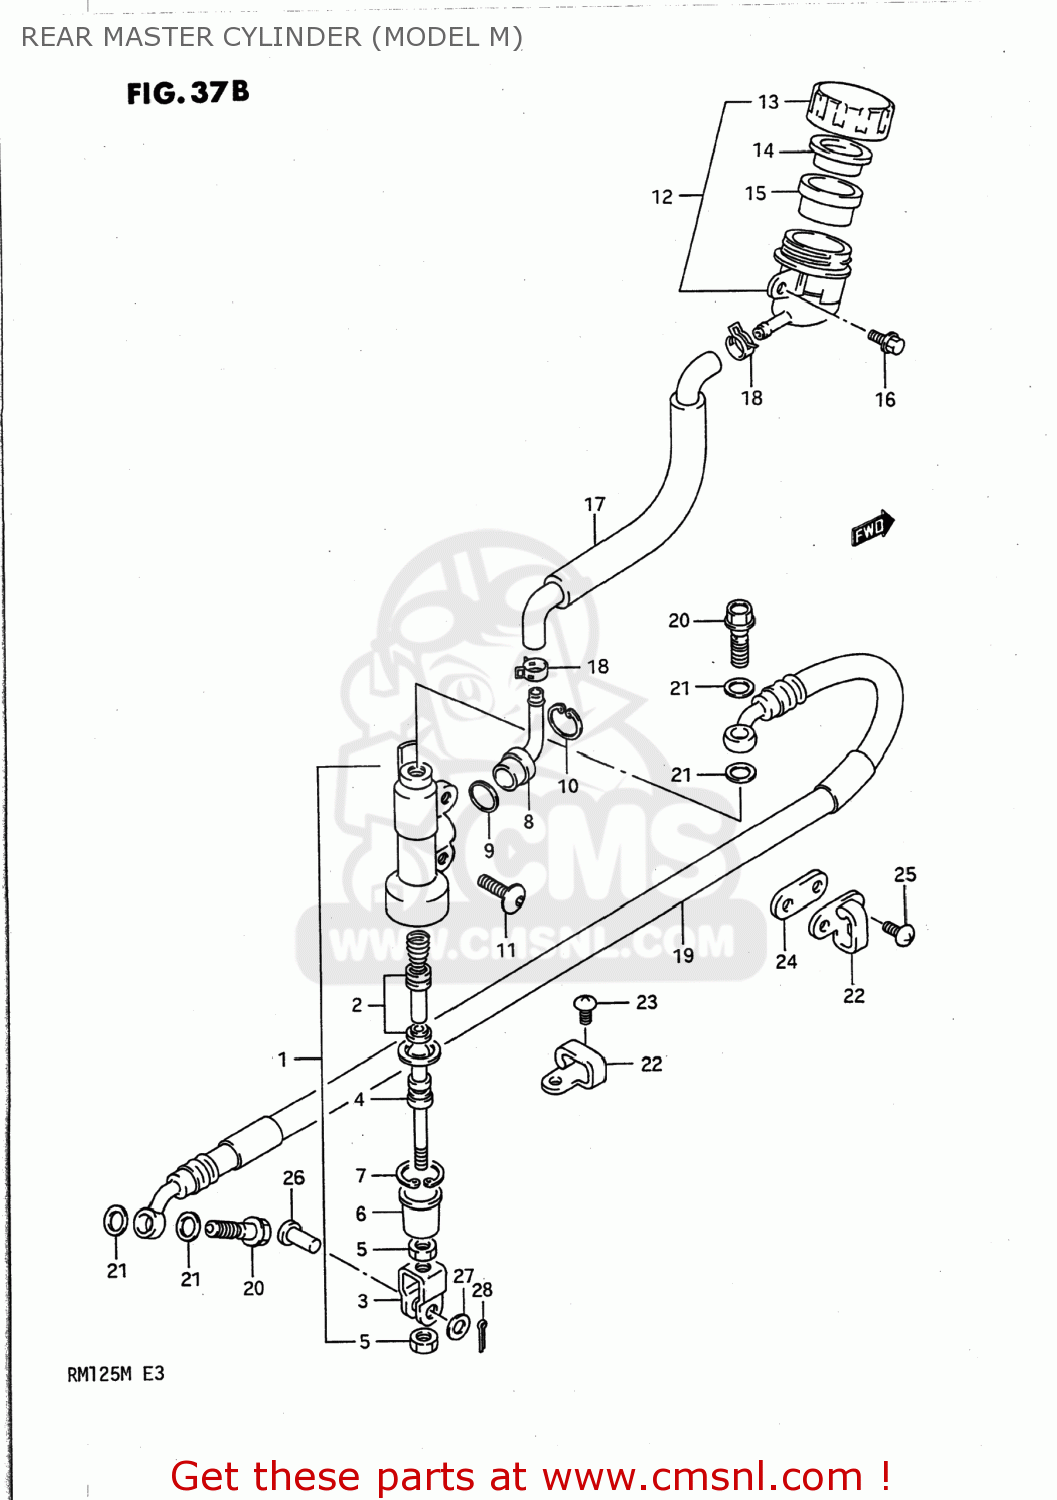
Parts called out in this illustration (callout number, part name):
1	CYLINDER ASSEMBLY,REAR MASTER
2	PISTON/CUP SET
3	YOKE
4	ROD,PUSH
5	NUT
6	BOOT
7	CIRCLIP
8	CONNECTOR
9	O RING
10	CIRCLIP
11	SCREW(6X16)
12	TANK ASSY,RR BRAKE RESERVOIR
13	CAP
14	PLATE
15	DIAPHRAGM
16	BOLT
17	HOSE,TANK
18	CLAMP,RESERVOIR HOSE
19	HOSE,REAR BRAKE
20	BOLT UNION
21	WASHER(10X15X1.5)
22	GUIDE,RR BRAKE HOSE
23	SCREW(5X10)
24	SEAT,RR BRAKE HOSE GUIDE
25	SCREW
26	PIN(8X20)
27	WASHER(8.5X13X1.6)
28	PIN
